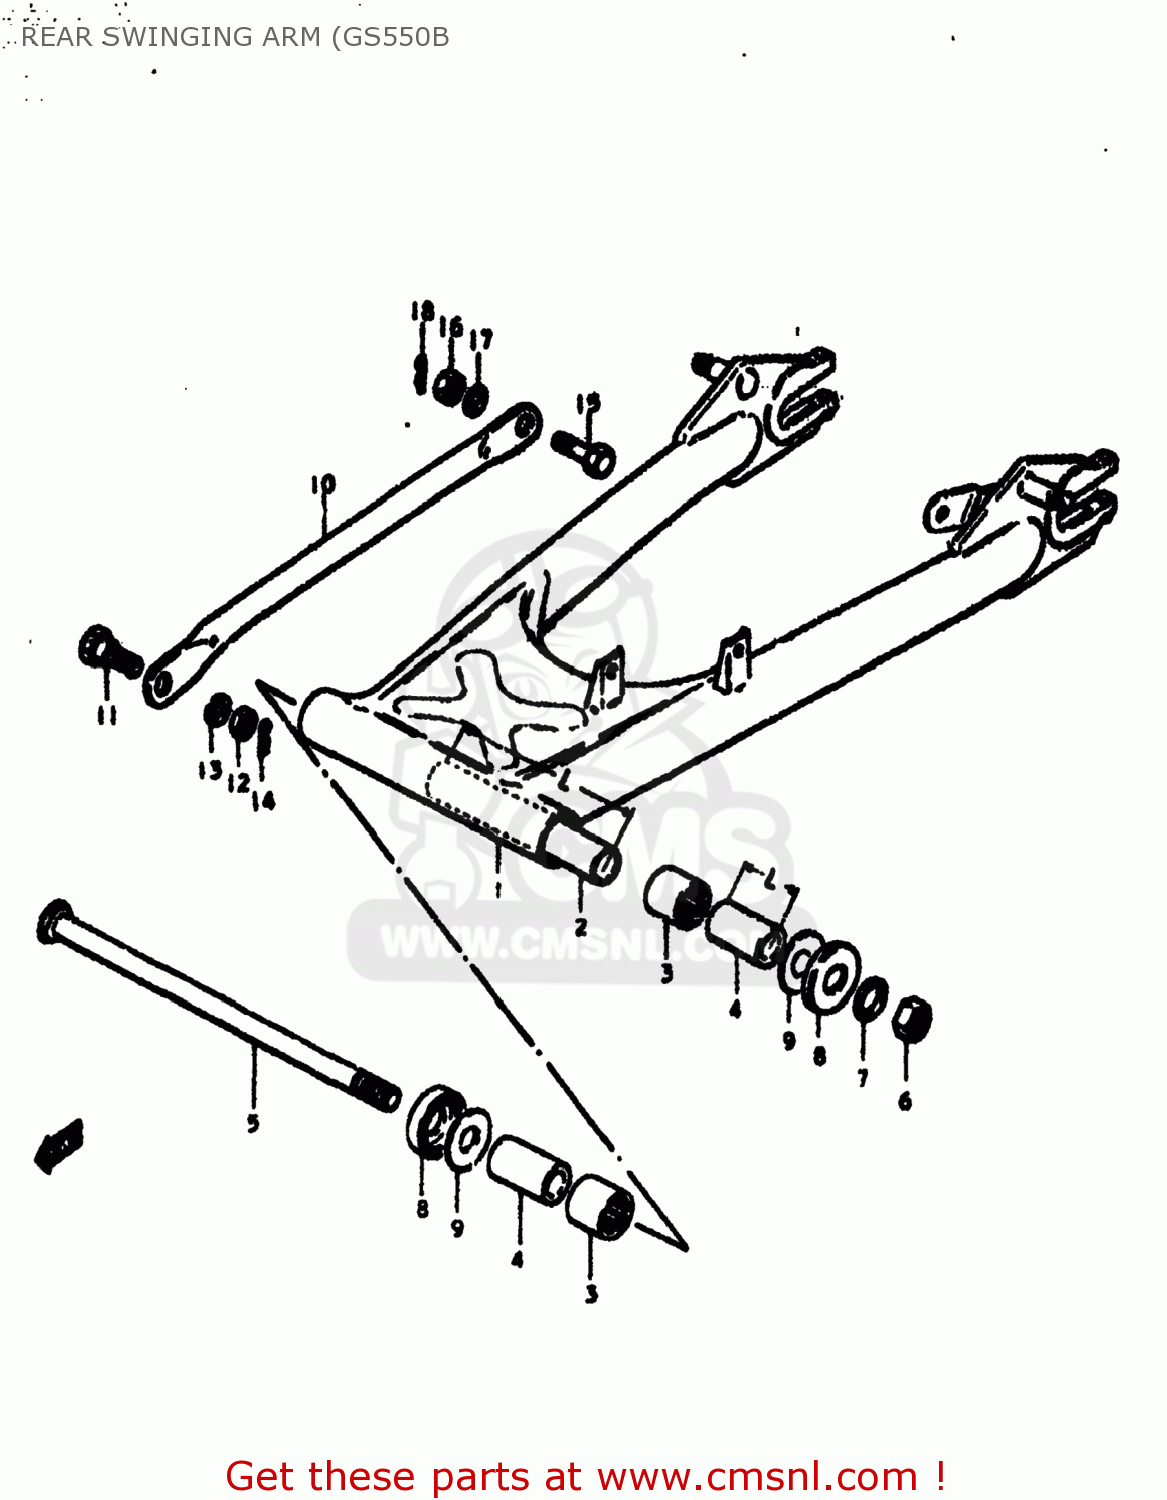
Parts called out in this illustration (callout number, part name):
1	SWING ARM ASSEMBLY,REAR
2	SPACER,SWING ARM,CENTER
3	BEARING(22X29X30)
4	SPACER,RR SWGARM PIVOT
5	SHAFT,REAR SWING ARM
6	NUT 14MM
7	WASHER
8	COVER,REAR SWING ARM DUST
9	WASHER(14.2X34X1)
10	TORQUE LINK,REAR
11	BOLT(10X24.5)
12	NUT
13	LOCK WASHER
14	CLIP
15	BOLT(10X31)
16	NUT
17	LOCK WASHER
18	CLIP
